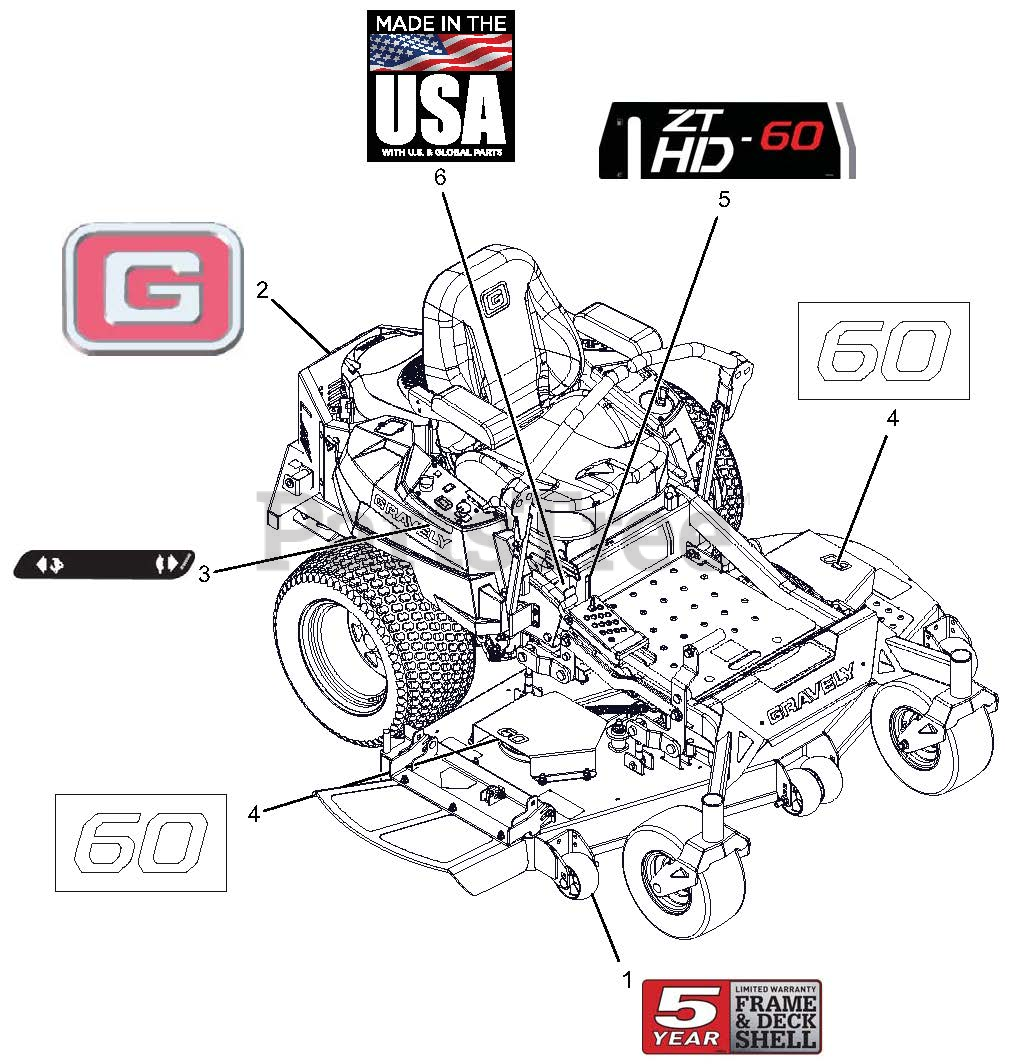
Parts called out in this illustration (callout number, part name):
1	DECAL,DECK WARRANTY-FAB GRVLY
2	DECAL, GRAVELY BRAND
3	DECAL, DASH DECAL
4	DECAL, 60"
5	DECAL - 60HD
6	DECAL, MADE IN USA
